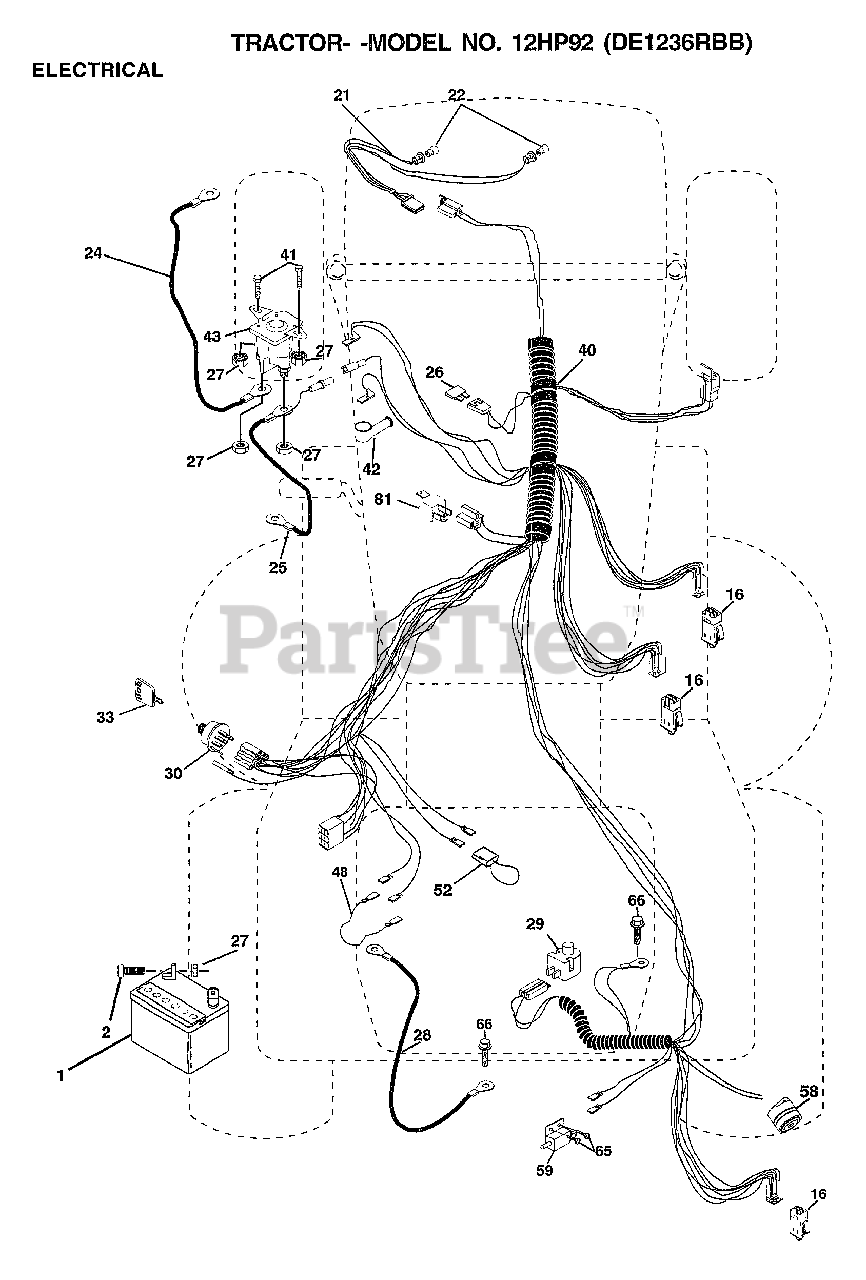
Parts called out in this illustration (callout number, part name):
2	BOLT LT
16	SWITCH INTERLOCK
21	HARNESS.ASM.LIGHT W/4152J
22	HEADLAMP BULB
24	"CABLE T, BATTERY"
25	CABLE.BATTERY.CRD
26	FUSE.15 AMP
27	NUT
28	"CABLE.GRD.6GA/18""BLACK"
29	SWITCH.PLUNGER
30	SWITCH.IGN.
33	KEY MLD GEN DELTA
40	HARNESS IGN CORD
41	BOLT HXHD FIN
48	ADAPTER AMMETER
52	PROTECTION LOOP
58	BUZZER CRD
59	SWITCH.FBI.CRD
65	SCREW
66	SCREW LT
81	RELAY ASSY T
